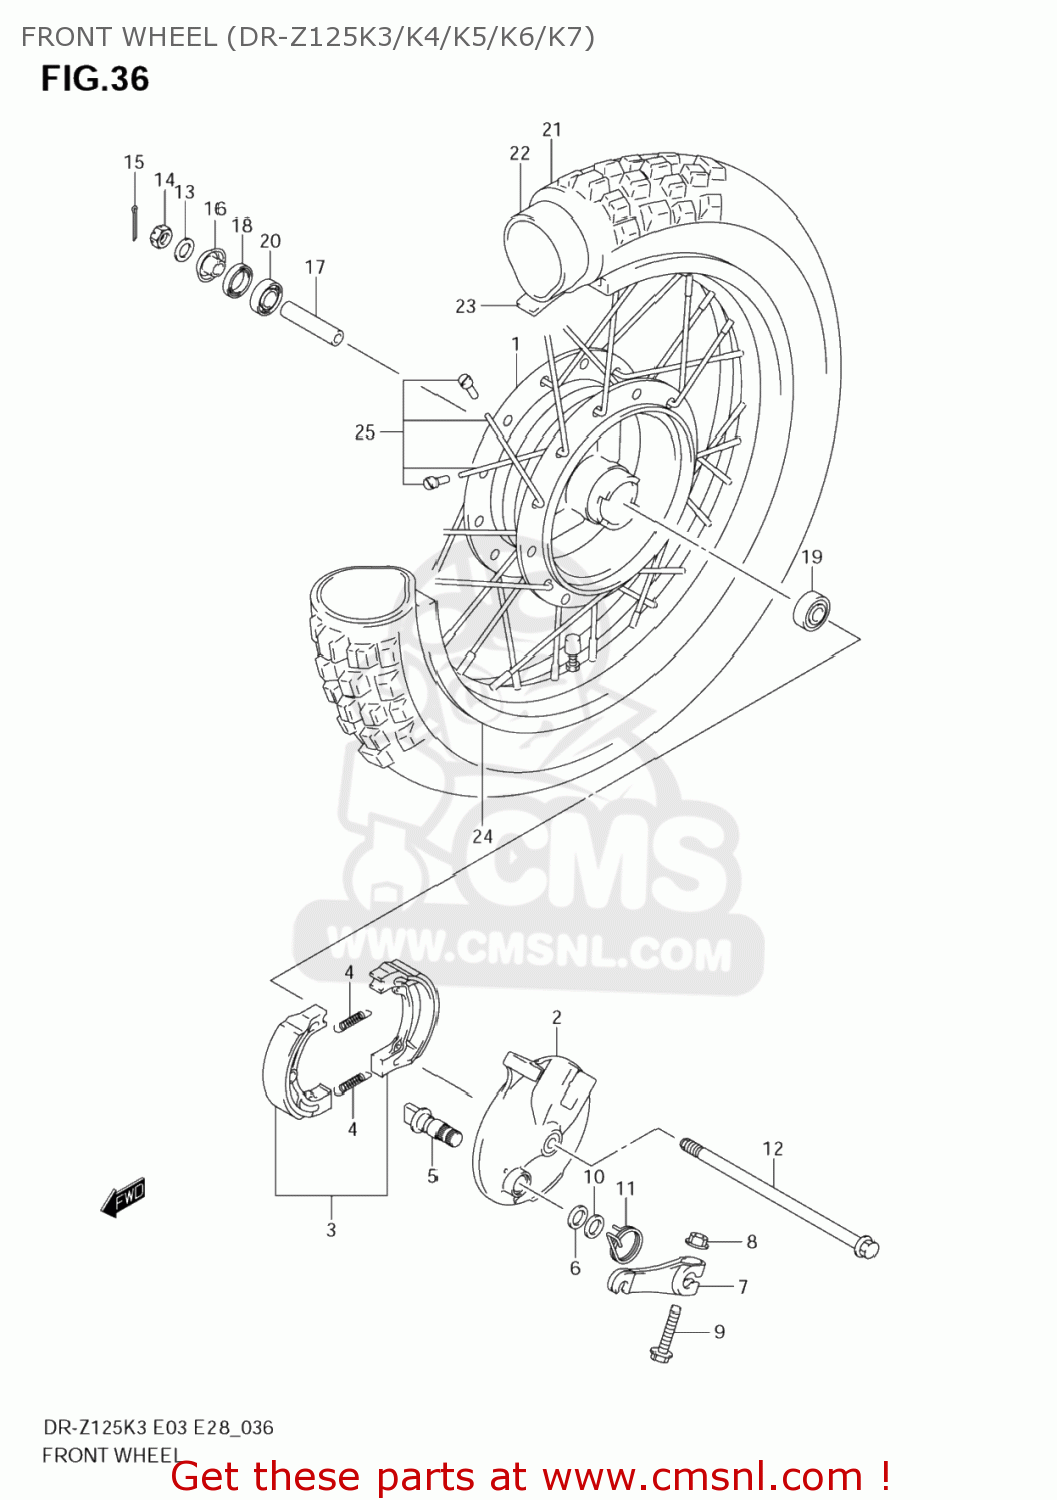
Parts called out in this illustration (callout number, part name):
1	HUB,FR WHEEL
2	PANEL,FR BRAKE ANCHOR
3	SHOE SET,BRAKE (NAS)
4	SPRING
5	CAM,FR BRAKE
6	O RING(D:2.5,ID:13.8)
7	LEVER,FR BRAKE CAM
8	NUT
9	BOLT
10	WASHER(14.5X22X1.6)
11	SPRING,FR BK CAM LEVER RETURN
12	AXLE,FR
13	WASHER(10.5X20X3.2)
14	NUT
15	PIN 20X20
16	SPACER,FR AXLE,R
17	SPACER(10.1X16X51)
18	SEAL,OIL(15X31X5)
19	BEARING
20	BEARING
21	TIRE,FR
22	TUBE ASSY,WHEEL INNER
23	PROTECTOR,WHL INR TUBE
24	RIM,FR WHEEL(17X1.40)
25	SPOKE SET,FR WHEEL
